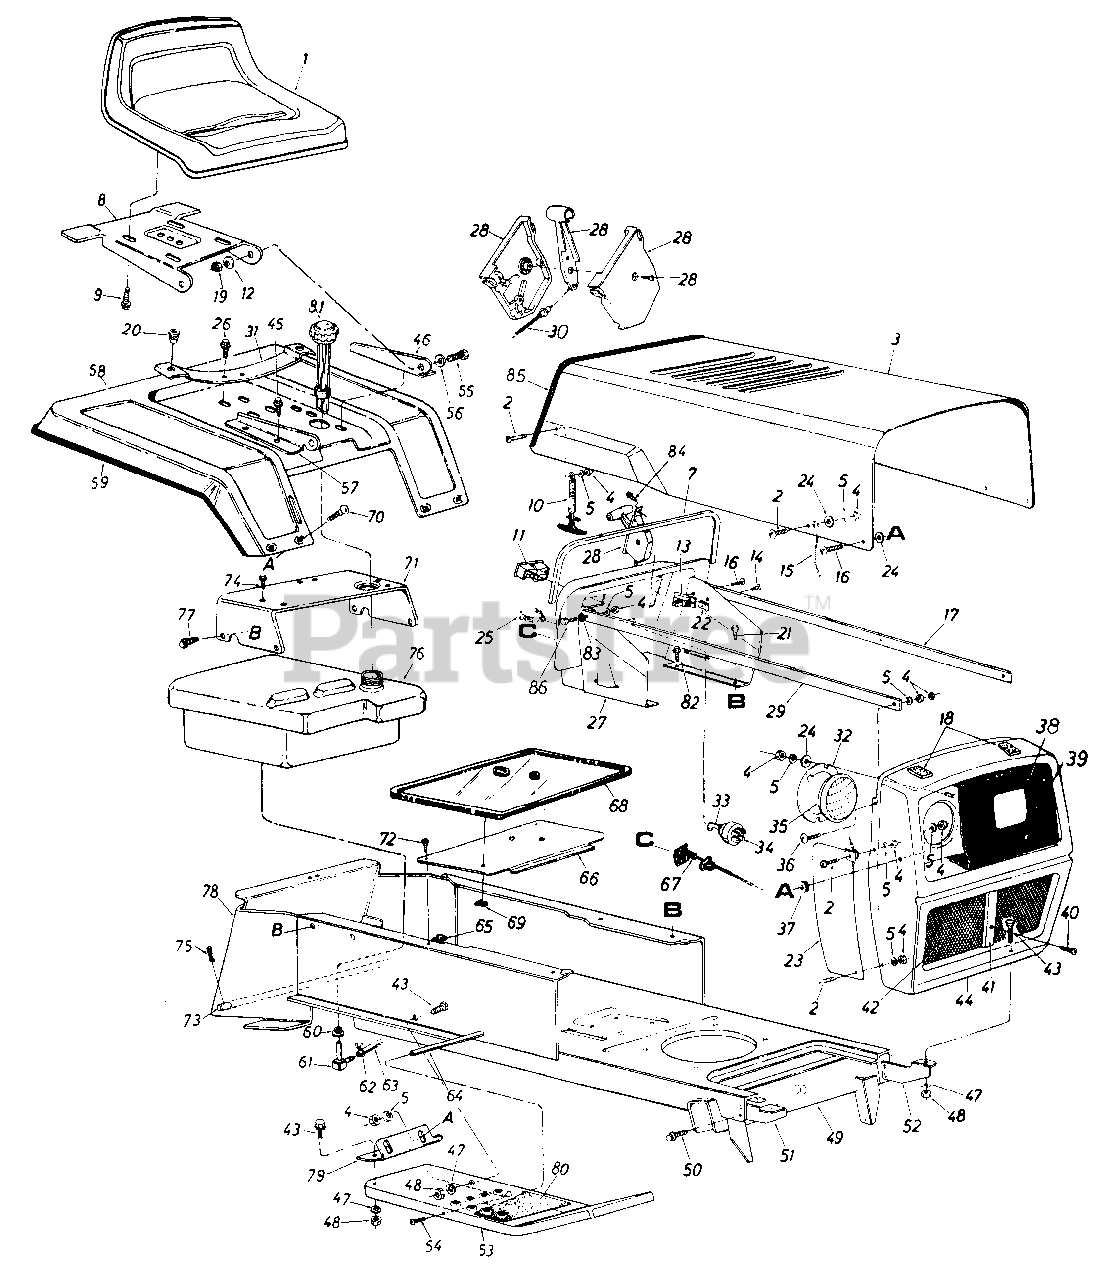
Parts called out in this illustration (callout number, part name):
1	Seat Assembly
2	Truss Mach. Scr. 1/4-20 x .50" Lg.*
5	L-Wash. 1/4 " Scr. *
7	Vinyl Molding Strip 29"
8	Seat Pivot Bracket
9	Hex Wash. AD 0 AB-Tap Scr. 318 x .75" Lg.
10	Hood Latch Ass'y.
11	Ammeter
12	Bell-Wash. .34" I.D. x .88" O.D.
13	Circuit Breaker 8 Amp.
14	Hex Tap Scr. #10 x .50" Lg.*
16	Truss Mach. Scr. 1/4-20 x .75" Lg.*
17	Grille Positioning Rod
18	PVC Foam Strip 1/2 X 1.OO" x 2.00" Lg.
19	Hex Cent. L-Nut 5/16-18 Thd.
20	Grommet
21	Hex Thd. Rolling Scr. 1/4" x .50" Lg.
22	Speed Nut #10Z
23	Grille Side Panel R.H.
24	Fl-Wash. '/4" I.D.
25	Light Switch
26	Hex Wash. Hd. Self-Tap Scr. 5/16-18 x .50" Lg.
27	Dash Panel Ass'y.
28	Throttle Control Box Comp.
29	Grille Positioning Rod
30	Throttle Control Wire
31	Seat Spring
32	Head Lamp Retainer
33	Ignition Key
34	Ignition Switch
35	Head Lamp
36	Truss Machine Scr. 1/4-20 x . 75 " Lg .
37	Rubber Wash. .50" I.D. x 1.00 O.D. x .25 Thk.
38	Headlight Bezel
39	Hex Wash. Hd. Scr. #8-32 x .38" Lg.
40	Truss Mach. Scr. #10-24 x .62" Lg.
41	Center Moulding
42	Grille Screen
43	Hex Scr. 5/16-18 x .75" Lg.*
44	Grille Ass'y.
45	Hex Wash. Hd. Self-Tap Scr. 5/16-18 x .50" Lg.
46	Seat Brkt. L.H.
47	L-Wash. 5/16" Scr.*
48	Hex Nut 5/16-18 Thd.*
49	Lower Frame Ass'y.
50	Hex Thd. Rolling AB 0 Scr. 5/16 x .75" Lg.
51	Grille Mount Brkt. R.H.
52	Grille Mount Brkt. L.H.
53	Running Board R.H.
54	Truss Mach. Scr. 5/16-18 x .75" Lg.*
55	Hex Bolt 5/16-18 x .75" Lg.*
56	Bell-Wash. .34" I.D. x .88" O.D.
57	Seat Brkt. R.H.
60	Bushing
61	90ø Nipple
63	Gas Line 46" Lg.
64	Running Board Rod
65	Speed Nut
66	Transmission Cover
67	Choke Control Comp.
68	Transmission Cover
69	Speed Nut 1/4" Stud
70	Carriage Bolt 1/4-20 x .50"
71	Seat Mounting Channel
72	B-Tap Scr. #10 x .50" Lg.
74	Hex Wash. Hd. Self-Tap Scr. 5/16-18 x .50" Lg.
75	Internal Cotter Pin
77	Hex Wash. Hd. AB-Tap Scr. 3/8 x .75" Lg.
78	Hitch Plate
82	Hex Thd. Rolling Scr. 5/16-24 x .75" Lg.
83	External Wash. 1/4" I.D.
84	Truss. Mach. Scr. #10 x .5" Lg.
85	Trim strip 30" Lg.
86	Truss Mach. Scr. 1/4-20 X 1.00
